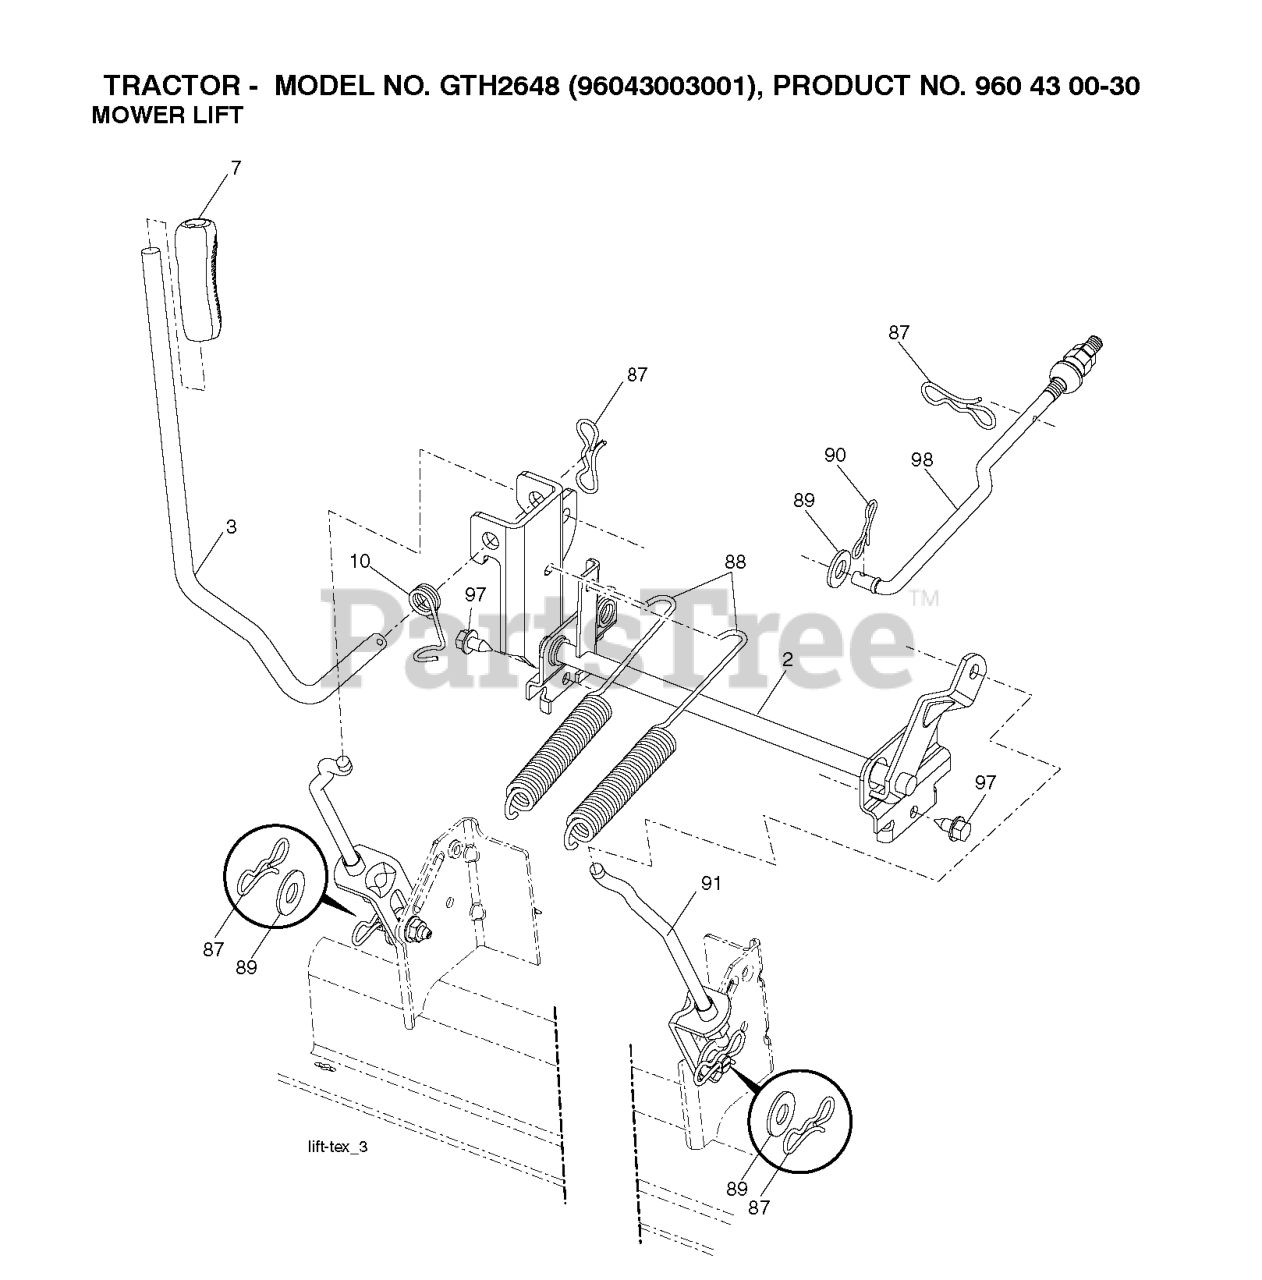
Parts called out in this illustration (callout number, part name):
2	SHAFT.ASM.LIFT.CROSS.H
3	LEVER.LIFT.HANDLE.GT
7	GRIP.LEVER.5625.ID
10	SPRING.TORSION.LIFT.HANDLE
87	PIN.COTTER.7/16.BOW TI.
88	SPRING.LIFT.ASSIST.GT2
89	WASHER.CLEAR.ZINC
90	PIN.COTTER.5/16.BOW TI
91	LINK.LIFT.ASM.REAR.GT.
97	SCREW, 3/8-16X3/4
98	LINK.ASM.SUSP.FRONT.MWR.10.5
